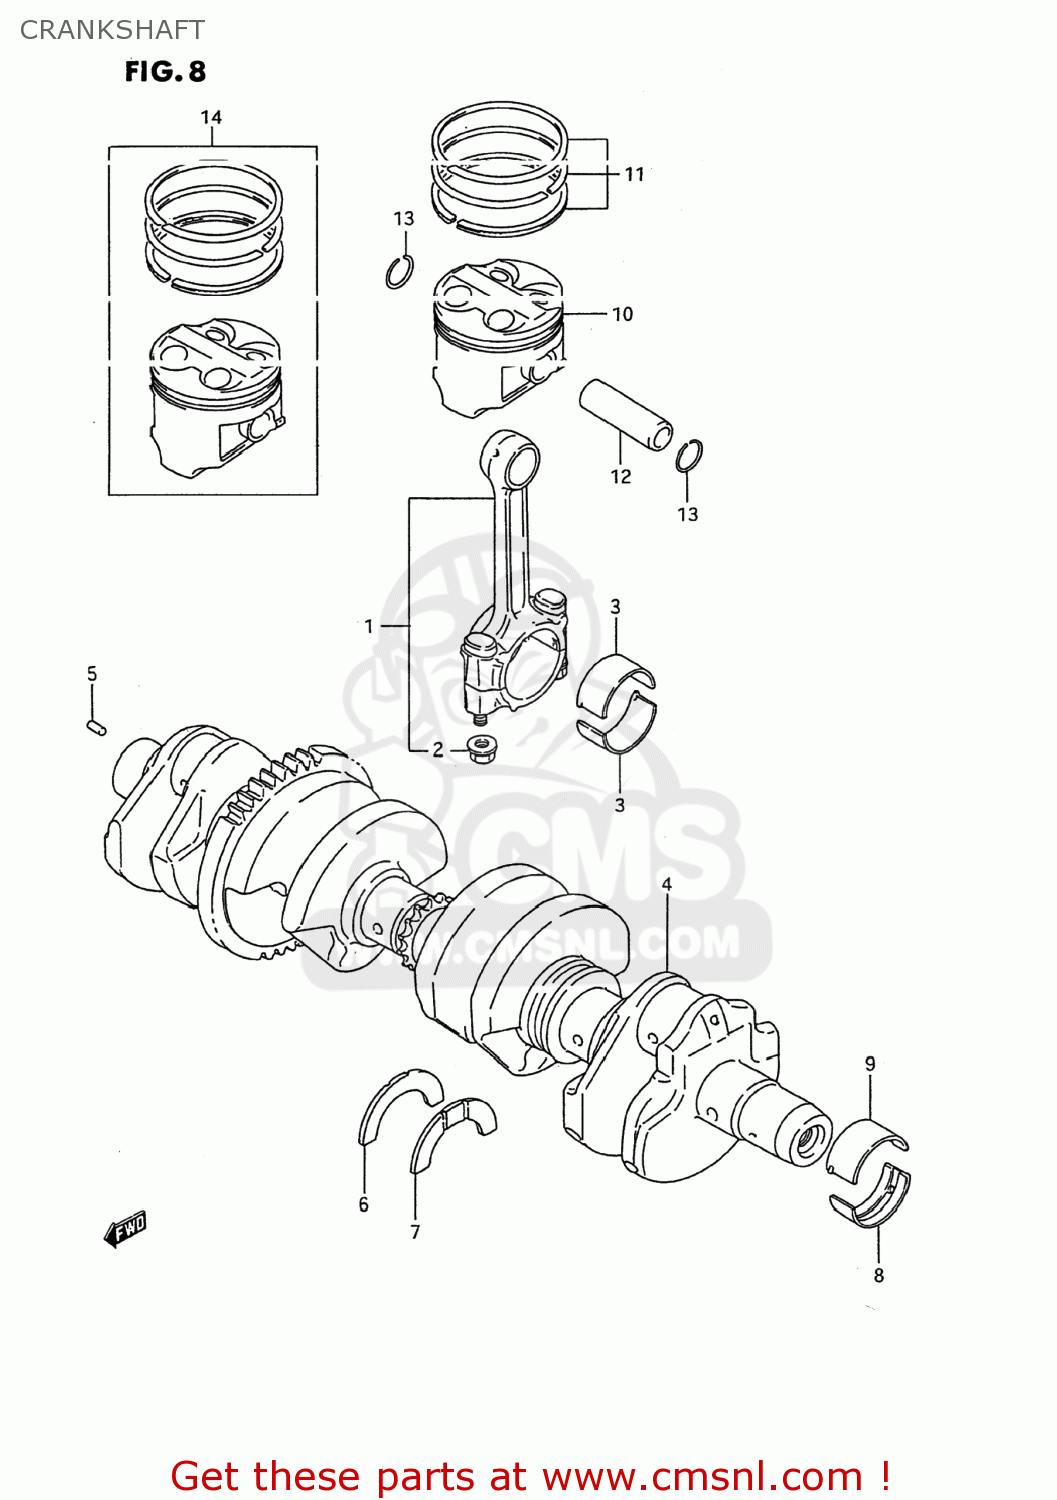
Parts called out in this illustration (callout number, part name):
1	ROD ASSEMBLY,CONNECTING
2	NUT
3	BEARING,CRANK PIN
4	CRANKSHAFT SET
5	PIN
6	PLATE,CRANK THRUST
7	PLATE,CRANK THRUST
8	BEARING,CRANKSHAFT LWR
9	BEARING,CRANKSHAFT UPR
10	PISTON
11	RING SET,PISTON
12	PIN,PISTON
13	CIRCLIP
14	PISTON SET (OS:1.0)
